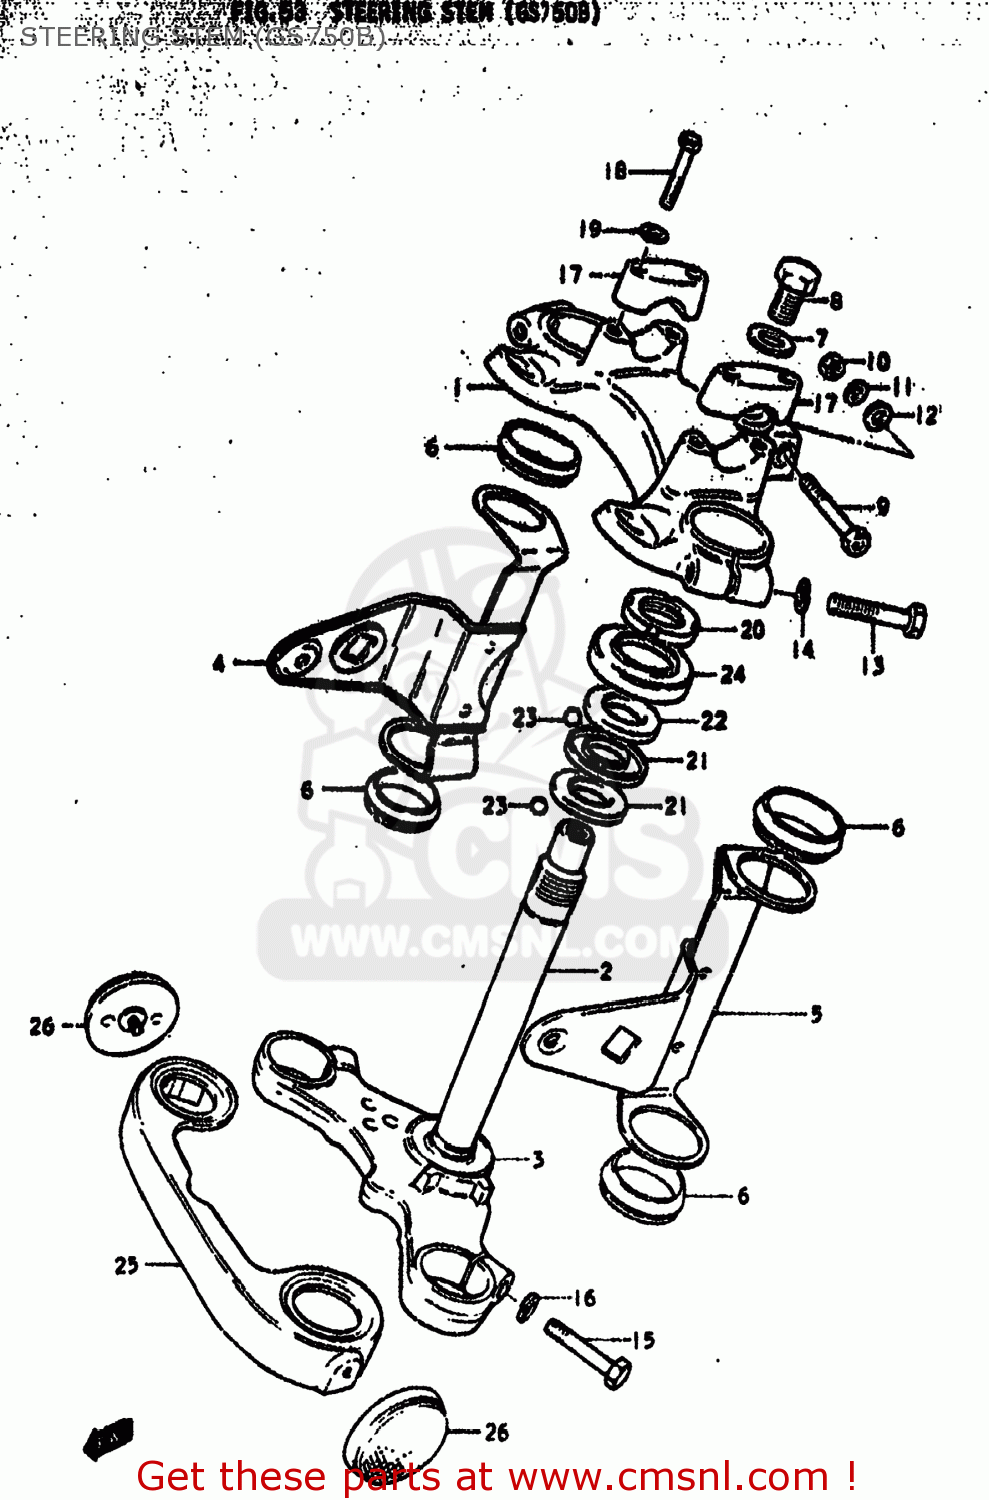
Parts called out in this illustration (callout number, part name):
1	HEAD,STEERING STEM
2	STEM,STEERING
3	RACE,STEERING OUTER LWR
4	BRACKET,HEADLAMP,RIGHT
5	BRACKET,HEADLAMP,LEFT
6	CUSHION,HEADLAMP BRACKET
7	WASHER
8	BOLT(12X20)
9	BOLT 8X50
10	NUT
11	LOCK WASHER
12	WASHER
13	BOLT 10X40
14	LOCK WASHER
15	BOLT 10X40
16	LOCK WASHER
17	HOLDER,HANDLEBAR
18	BOLT
19	LOCK WASHER
20	NUT,STEERING STEM(25X44X10)
21	LACE,STEERING INNER LWR
22	LACE,STEERING OUTER UPR
23	BALL
24	DUST SEAL,STEERING UPR
25	COVER,FRONT FORK
26	REFLEX REFLECTOR,FR
